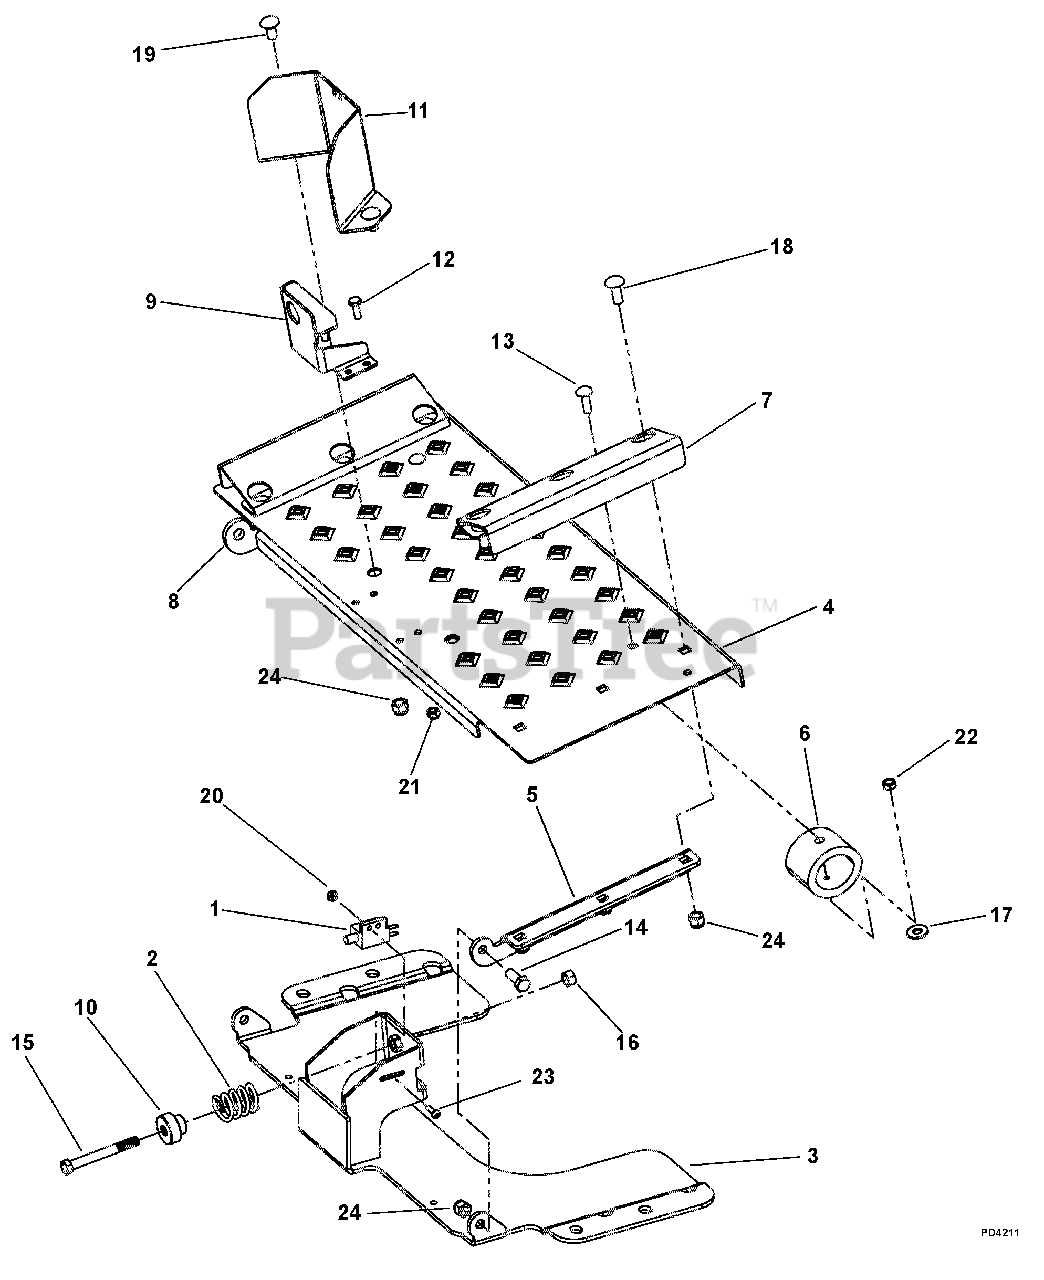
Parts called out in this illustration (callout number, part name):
1	Switch
2	Spring
3	Weldment, Platform
4	Plate, Platform
5	Plate, Platform Tab
6	Bumper, Miner GBR-6
7	Wedge, Platform
8	Plate, Platform Tab LH
9	Anchor, Operator Presence Control
10	Washer, Spring
11	Cover, Operator Presence Control
12	Bolt, Hex M12 x 1.75 x 25
13	Bolt, Round Head Square Neck .31-18 x 1.00
14	Bolt, JDS19-16 UNC
15	Bolt, Hex .38-16 x 3.25
16	Nut, Hex .31-18
17	Washer, Flat .38 x .875 x .083
18	Bolt, Round Head Square Neck .31-16 x 1.00
19	Bolt, Round Head Square Neck .31-16 x .75
20	Nut, Locking, Nylon 10-24 With Insert
21	Nut, Locking, Nylon .250-20
22	Nut, Locking, Nylon .312-18
23	Screw, Machine 10-24 x .62 Pan Head
24	Nut, Locking, Nylon .38-16
